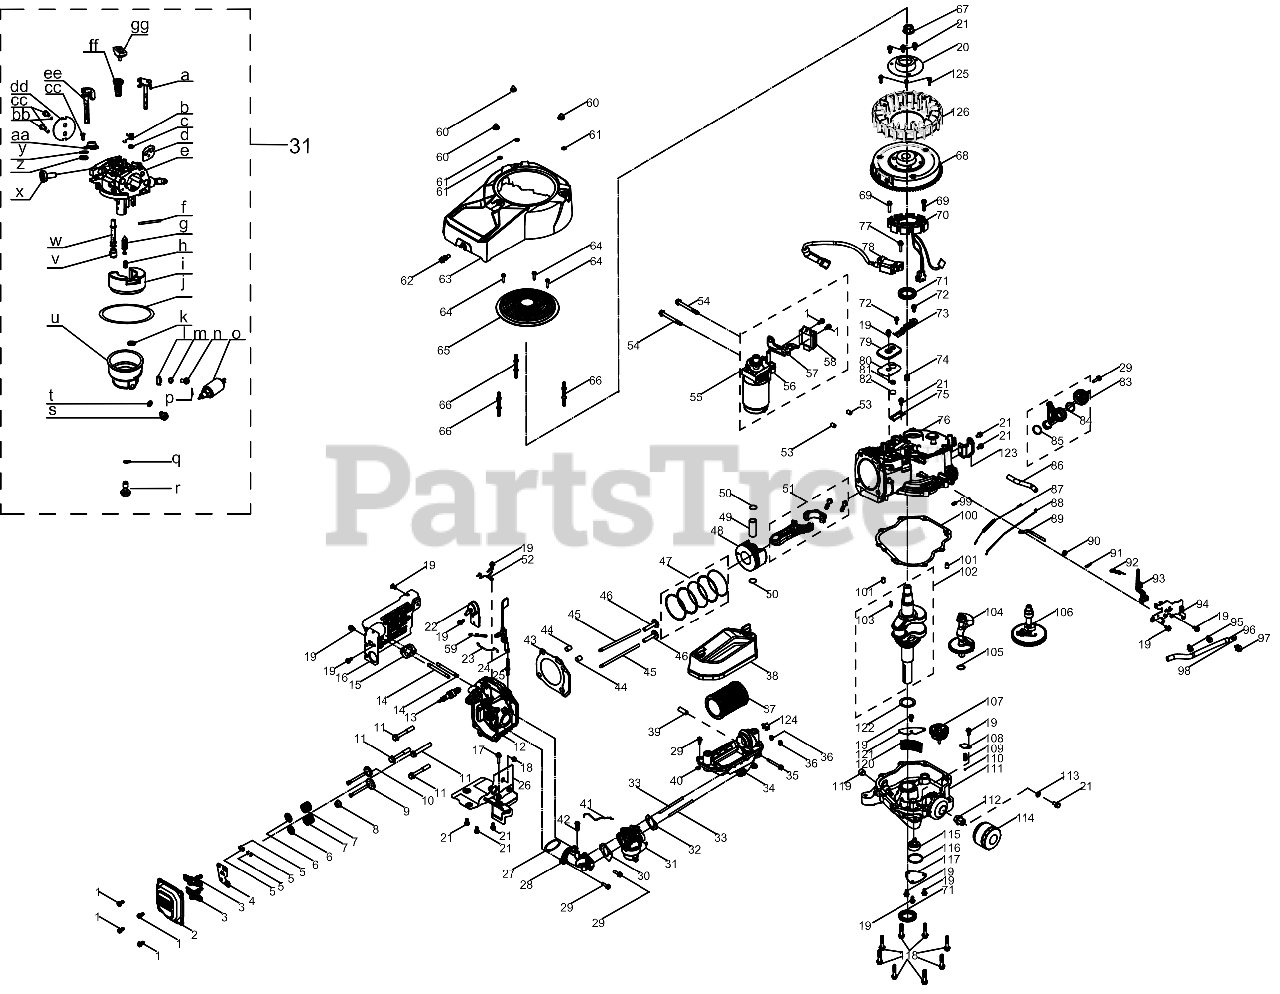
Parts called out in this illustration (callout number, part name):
1	BOLT M6 x 16
2	VALVE COVER
3	ROCKER ARM ASSEMBLY
4	ROCKER ARM BASE
5	VALVE CAP
6	VALVE SPRING SEAT
7	VALVE SPRING
8	INTAKE VALVE SEAL
9	INTAKE VALVE
10	EXHAUST VALVE
11	BOLT M10-1.25 x 70
12	CYLINDER HEAD
13	SPARK PLUG
15	EXHAUST GASKET
16	ENGINE SHROUD
17	BOLT M6-1 x 25 GR8.8
18	BOLT M6-1 x 10 GR8.8
19	BOLT M6-1 x 14 GR8.8
20	FLYWHEEL HUB COVER
21	BOLT M6-1 x 12 GR8.8
22	THERMAL SWITCH
23	THERMAL LEVER
24	SHIELD ASSEMBLY
25	PIVOT VANE STUD
27	O-RING 36 x 2.5
28	INTAKE MANIFOLD
29	BOLT M6 x 22
30	INTAKE GASKET
31	CARBURETOR
32	AIR FLTER GASKET
33	STUD M6-1.00 x 92
34	AIR FILTER BASE ASSEMBLY
35	SCREW M6-1:50:CL5.
37	AIR FILTER W/PREFILTER
38	AIR FILTER COVER ASSEMBLY
39	BUSHING - 11X6X30
40	CARB FUEL DRAIN GASKET
41	CHOKE LEVER
42	SELF TAPPING SCREW 4.8 x 16
43	CYLINDER HEAD GASKET
45	PUSH ROD - INDIVIDUAL
46	TAPPET
47	PISTON RING SET
49	PISTON PIN
50	PISTON PIN SNAP RING
51	CONNECTING ROD ASSEMBLY
54	BOLT M8-1.25 x 80
56	ELECTRIC STARTER ASSEMBLY
59	IDLE SPRING
60	ACORN NUT
64	BOLT 5.5 x 25
65	FLYWHEEL SCREEN
66	STUD M6X95
67	NUT M20 x 1.5
69	BOLT M5 x 28
70	ALTERNATOR
71	OIL SEAL - 35X52X7
72	BOLT M5-.8 x 10
73	WIRE PLATE
75	BREATHER SCREEN
77	BOLT-M6-1 x 28 GR8.8
78	IGNITION COIL
79	BREATHER COVER
80	BREATHER COVER GASKET
81	BREATHER VALVE SPRING
82	BREATHER VALVE
83	DIPSTICK ASSEMBLY
86	BREATHER HOSE
87	THROTTLE DAMPENING SPRING
88	THROTTLE LINKAGE
89	GOVERNOR GEAR SHAFT
90	GOVERNOR SEAL
91	COTTER PIN
92	GOVERNOR SPRING
93	GOVERNOR ARM ASSEMBLY
94	CONTROL BRACKET ASSEMBLY
95	HOSE CLAMP
96	FUEL HOSE 6.3 x 12.5 x 250
97	FUEL LINE SUPPORT CLAMP
100	CRANKCASE GASKET
101	DOWEL PIN
102	CRANKSHAFT
103	FLYWHEEL KEY
104	BALANCE SHAFT
105	WASHER 17.2 x 26 x 1
106	CAMSHAFT ASSEMBLY
107	GOVERNOR GEAR
108	PRESSURE RELEASE COVER
109	PRESSURE RELEASE SPRING
110	OIL PUMP STEEL BALL
111	CRANKCASE COVER
112	SCREW JOINT OIL FILTER ADAPTER
113	WASHER - 6.2X1.5X13
114	ENGINE OIL FILTER
115	OIL PUMP ASSEMBLY
117	OIL SEPARATOR
118	BOLT M8 x 40
119	ENGINE PLUG 3/8 NPT
120	FILTER SCREEN
121	OIL SCREEN PLATE
122	WASHER - 35.4X1X52
125	BOLT M5 x 18
126	COOLING FAN
